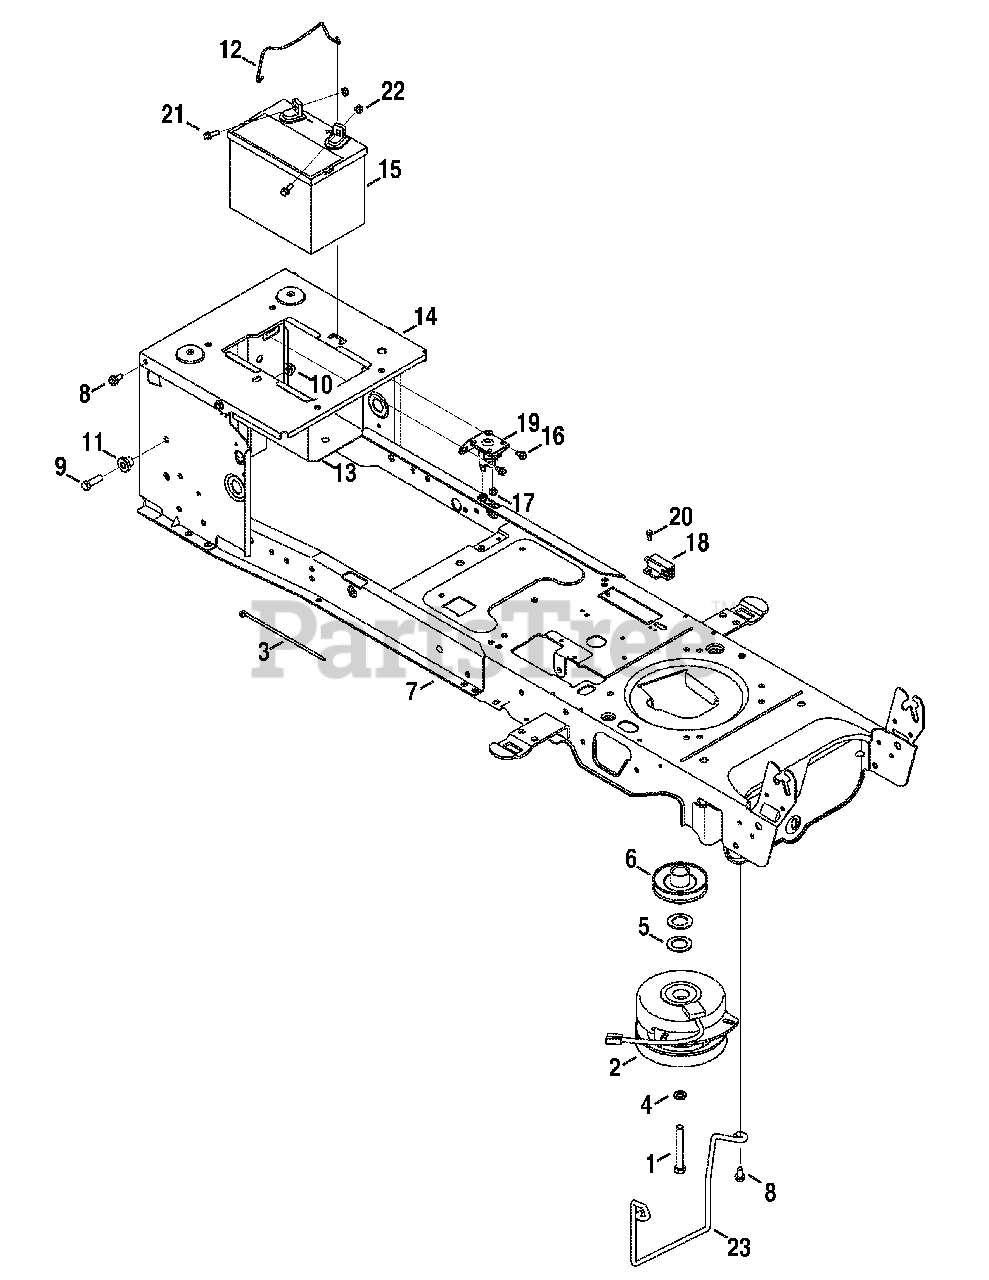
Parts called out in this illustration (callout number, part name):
1	Hex Head Screw, 7/16-20:3.50
2	Electric PTO Clutch
3	Cable Tie, 3/16 x .05 x 7.4
4	Lock Washer, 7/16
5	Flat Washer, 1.031 x 1.620 x .095
6	Electric PTO Engine Pulley
7	Frame
8	Taptite Screw, Indented Washer, 5/16-18:.750
9	Hex Head Screw, 3/8-16:1.25
10	Flangelock Nut, 3/8-16
11	Shoulder Spacer, .38 x 1.0 x .70
12	Battery Holder Rod
13	Battery Tray
14	Seat Frame Bracket
15	Battery
16	Taptite Screw, 1/4-20:0.375
17	Flangelock Nut, 1/4-20
18	Interlock Switch
19	Solenoid, 12 V
20	Shoulder Screw, #10-32:.500
21	Hex Head Flange, 1/4-20:.75
22	Sems Nut, 1/4-20
23	Belt Keeper Rod
